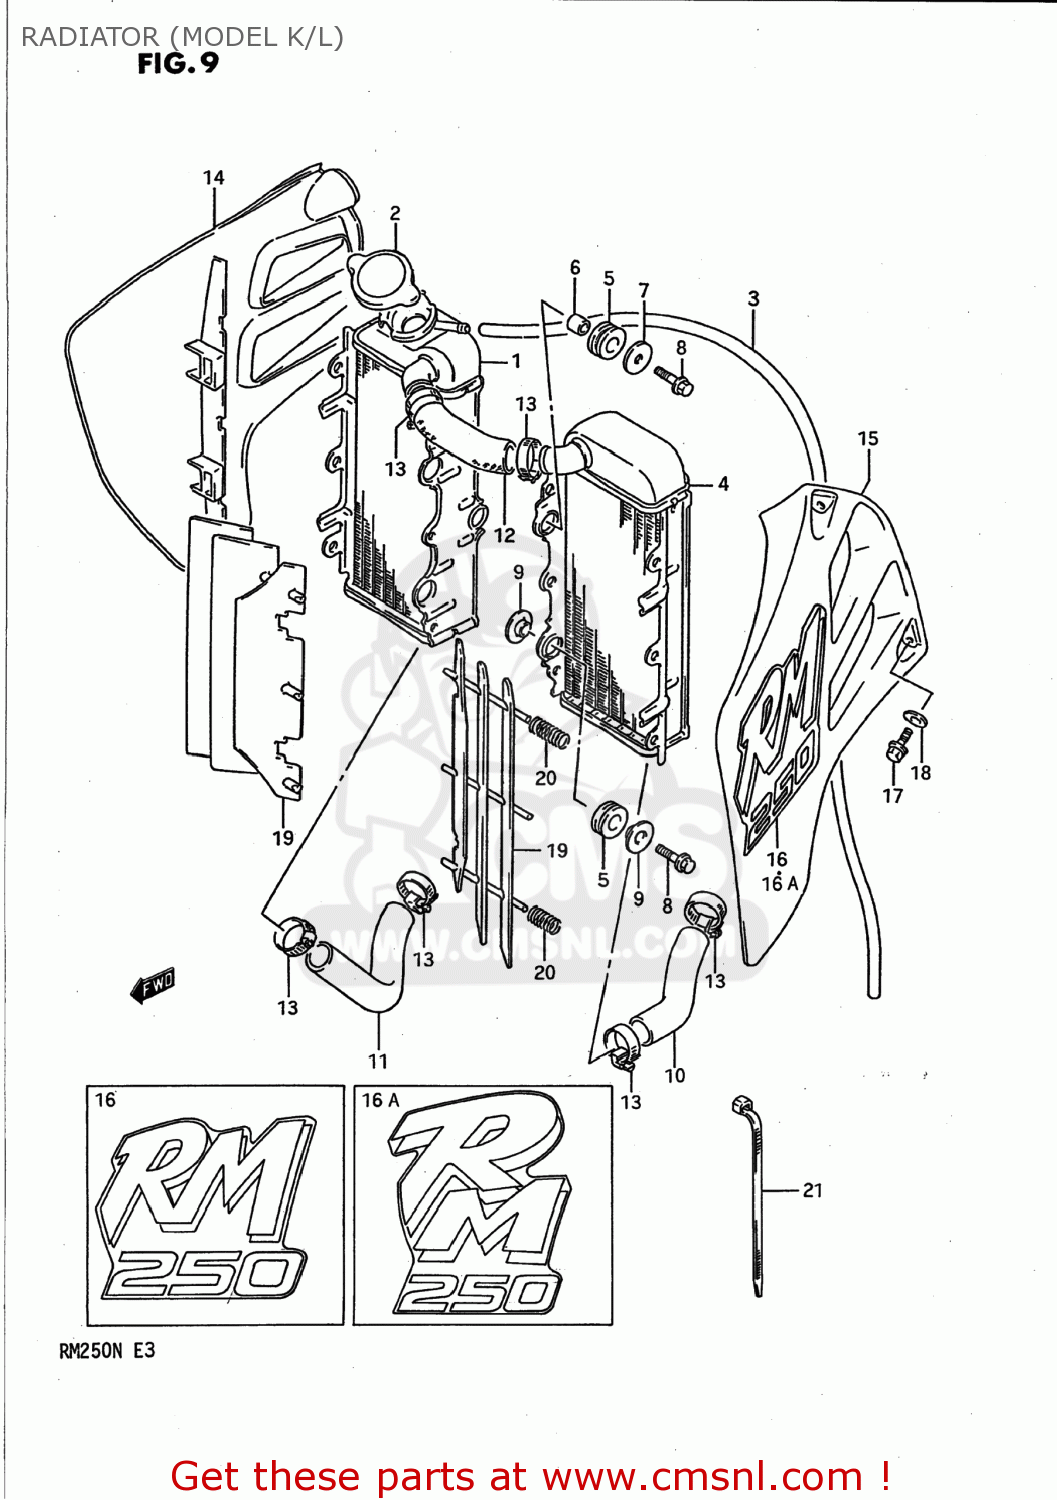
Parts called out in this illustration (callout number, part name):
1	RADIATOR ASSEMBLY,WATER
2	CAP,RADIATOR 1.1
3	HOSE
4	RADIATOR,WATER,L
5	CUSHION,RADIATOR LWR
6	SPACER(6.5X10.5X12)
7	WASHER (6.5X24X1.2)
8	BOLT
9	WASHER,RDTR SPRT
10	HOSE,RADIATOR INLET
11	HOSE,RADIATOR OUTLET
12	HOSE,RADIATOR
13	CLAMP
14	COVER,RADIATOR,R
15	COVER,RADIATOR,L
16	EMBLEM,RADIATOR COVER
16A	EMBLEM,RADIATOR COVER
17	BOLT
18	GASKET(6.5X20X1.5) (NAS)
19	LOUVER,RADIATOR
20	SPRING
21	CLAMP(L:165)
